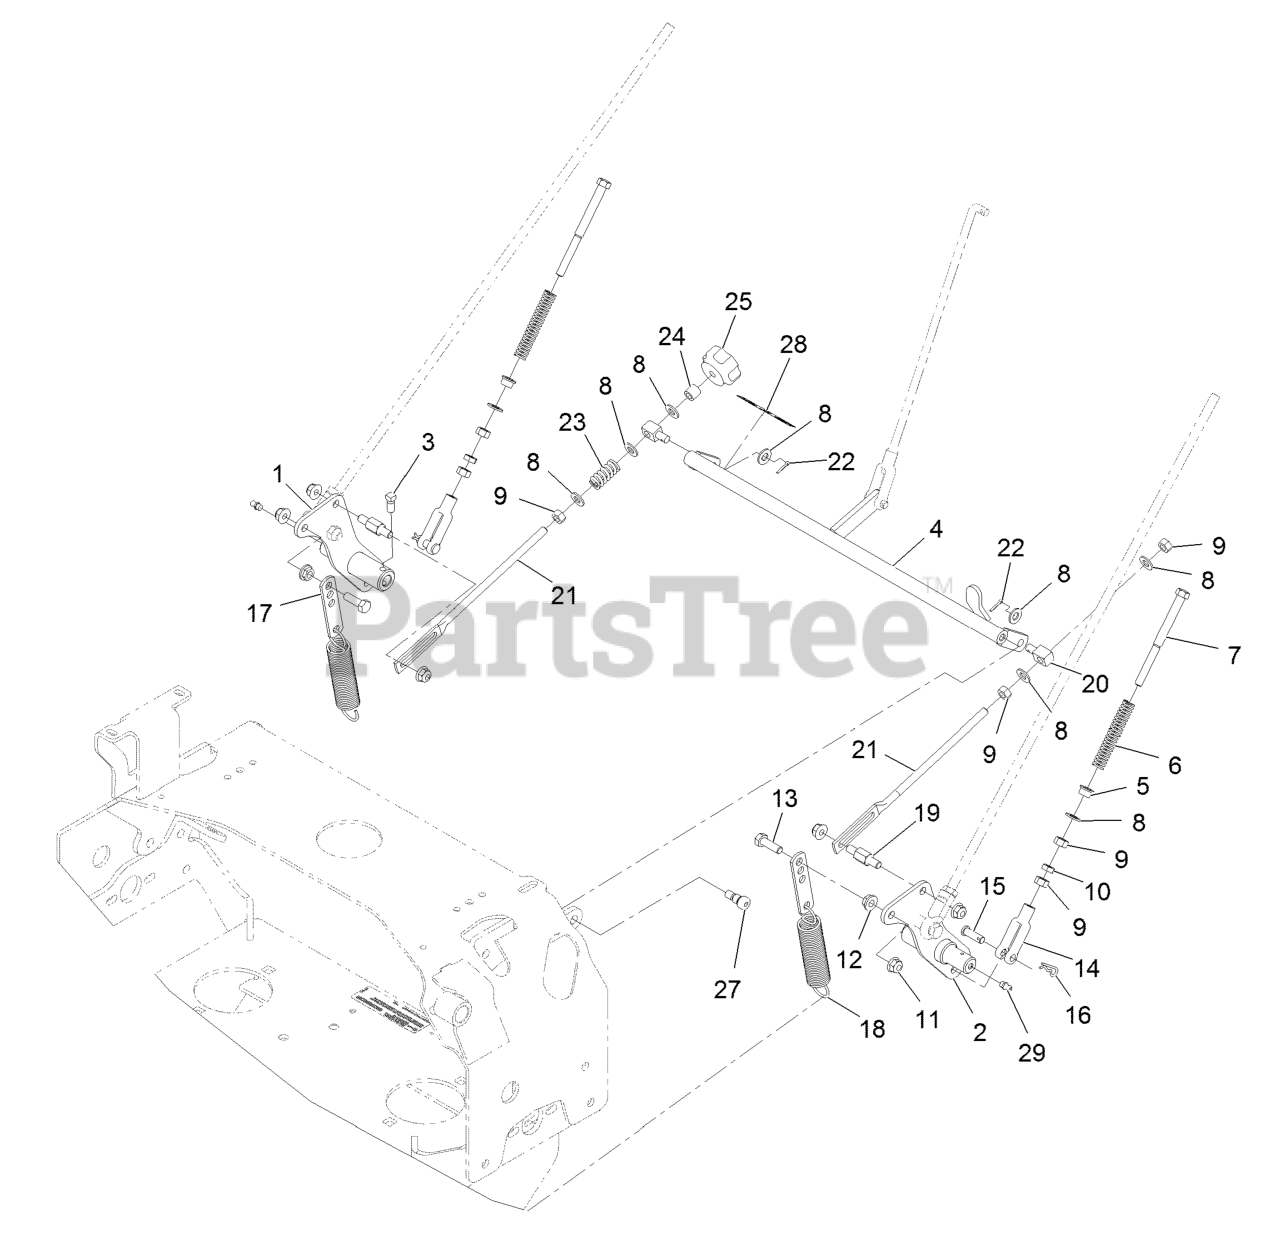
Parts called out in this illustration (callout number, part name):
1	Weld, Motion Control, Rt
2	Weld, Motion Control, Lt
3	Setscrew-5/16-18 X 5/8
4	Weld, Speed Control
5	Bushing-Flanged
6	Spring, Neutral Return
7	Bolt-Neutral Return
8	Washer-5/16 SAE
9	Nut-Hex 5/16-24
10	Nut-Jam 5/16-24
11	Nut-Nyloc 5/16-18 Flg
12	Nut-Whizlock 5/16-18
13	Screw-HH 5/16-18 X 1
14	Yoke-Adjustable
15	Pin-Clevis 5/16 X 1 49/64
16	Hairpin-Cotter
17	Tab-Spring, Extension
19	Pin, Motion Control
20	Swivel-Adjustable, Short
21	Link-Control, Speed
22	Pin-Cotter 3/32 X 1/2
23	Spring-Compression
25	Knob-Tracking
27	Screw-Sh 5/16-18 X 1 3/8
28	Decal-Tracking Adjustment
29	Zerk-1/4-28 Str
